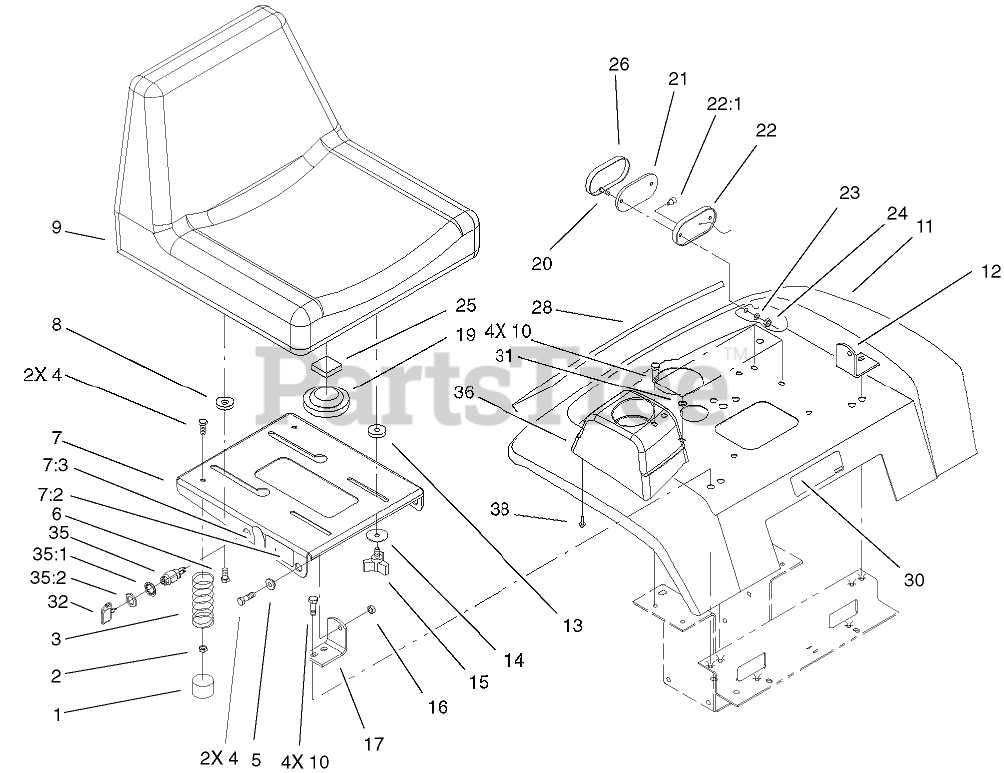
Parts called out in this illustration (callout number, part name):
1	CAP-PROTECTOR
2	NUT-LOCK, NI
3	SPRING-COMPRESSION
4	SCREW-HH
5	BUSHING
6	BOLT-SHOULDER
7	SUPPORT SEAT ASM
7:2	DECAL-DANGER
7:3	DECAL
8	SPACER-NYLON
9	SEAT
10	SCREW-HWHTF
12	BRACKET-PIVOT, LH
13	SPACER-NYLON
14	WASHER
16	NUT-LOCK, NI
17	BRACKET-PIVOT, RH
19	SWITCH-SEAT
20	SCREW-PPH
21	Reflector (only on: 73429)
22	Base-Taillight (only on: 73449)
22:1	Bulb (only on: 73449)
23	Washer-Lock/Int (only on: 73449)
24	NUT-LOCK, NI
25	FOAM-SWITCH, SEAT
26	Lens-Tail Light (only on: 73449)
28	DECAL - REAR FENDER
30	DECAL - USA
31	Washer-Lock/Ext (only on: 73449)
32	KEY-IGNITION
35	STARTER SWITCH ASM
35:1	WASHER-TOOTH, INTERNAL
35:2	NUT-HH
36	HOLDER-CUP
38	SCREW-HHFTF
